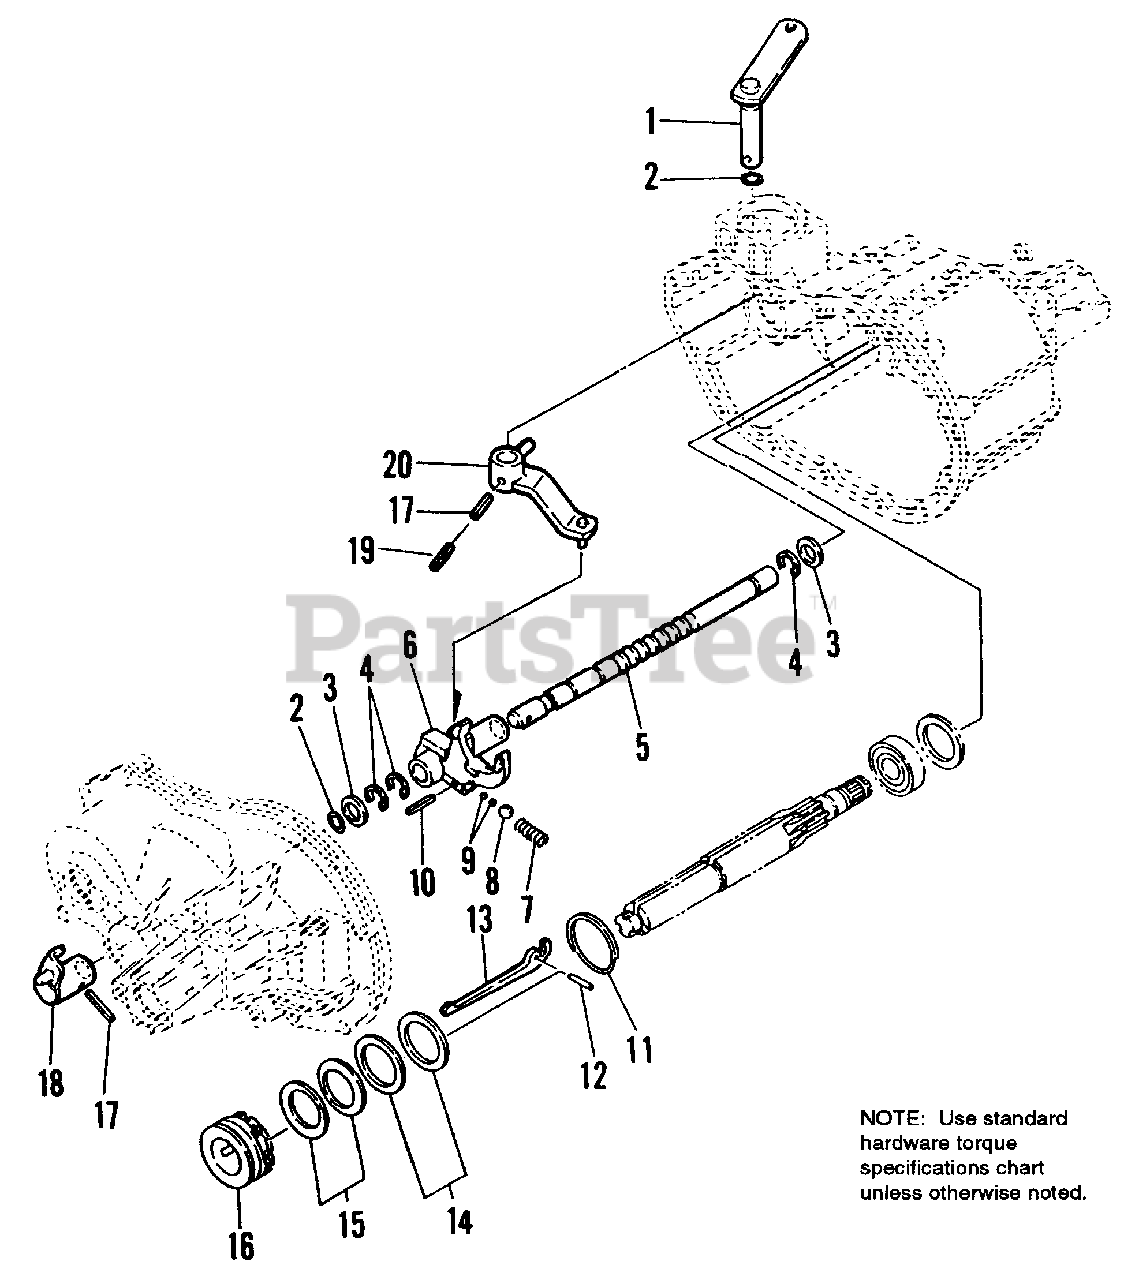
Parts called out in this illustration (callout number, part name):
4	RING, lnternal Snap
5	SHAFT, Fork
6	FORK, Shift
11	SPRING, Ringed
14	WASHER ASSY.
15	CONICAL SPRING ASSY.
18	ARM, Interlock
